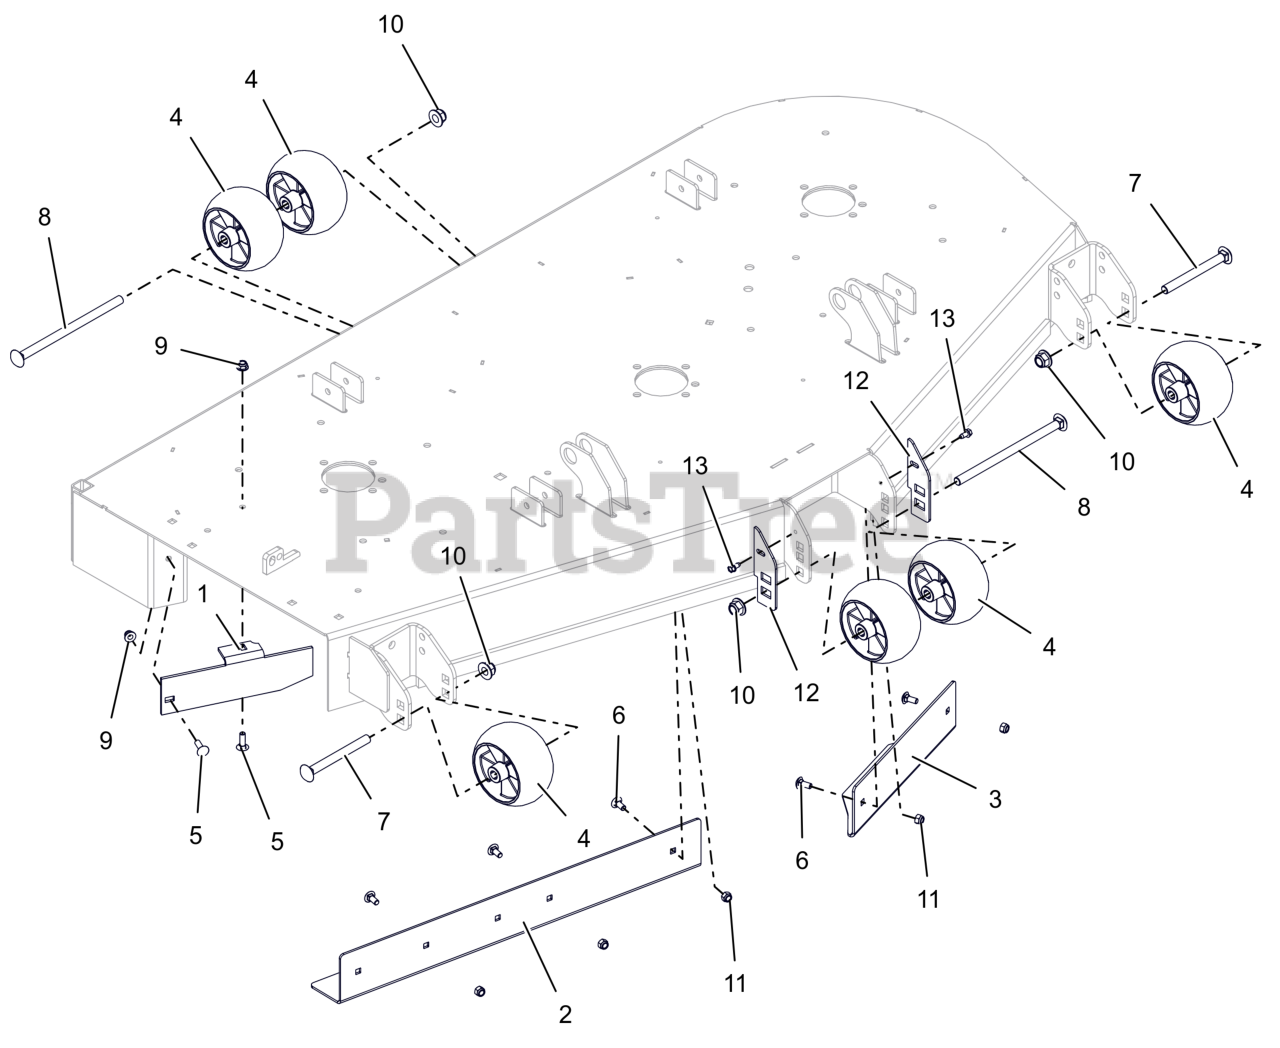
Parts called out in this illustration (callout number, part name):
1	BAFFLE, 60" DISCHARGE
2	BAFFLE, 60" RH VACUUM (ORANGE)
3	BAFFLE, 60" LH VACUUM (ORANGE)
4	WHEEL, ANTI SCALP - 5X3 CTR W/RIBS
5	BLT,RHSN .31-18X1.00 G5 ZCC
6	BLT,RHSN .31-18X.75 G5 ZCC
7	BLT, RHSN .50-13X5.00 G5 ZCC
8	BTL,RHSN .500-13 X 8.5S G5 ZCC
9	NUT,LK-NYL-FLG .31-18 G5ZC120
10	NUT,NYL-FLG .50-13 GF ZCC
11	NUT,NYL .31-18 G5 ZCC
12	PLATE, ANTI SCALP WHEEL 60" (ORANGE)
13	SCR-TAP .25-20X.50 HWH ZCC
